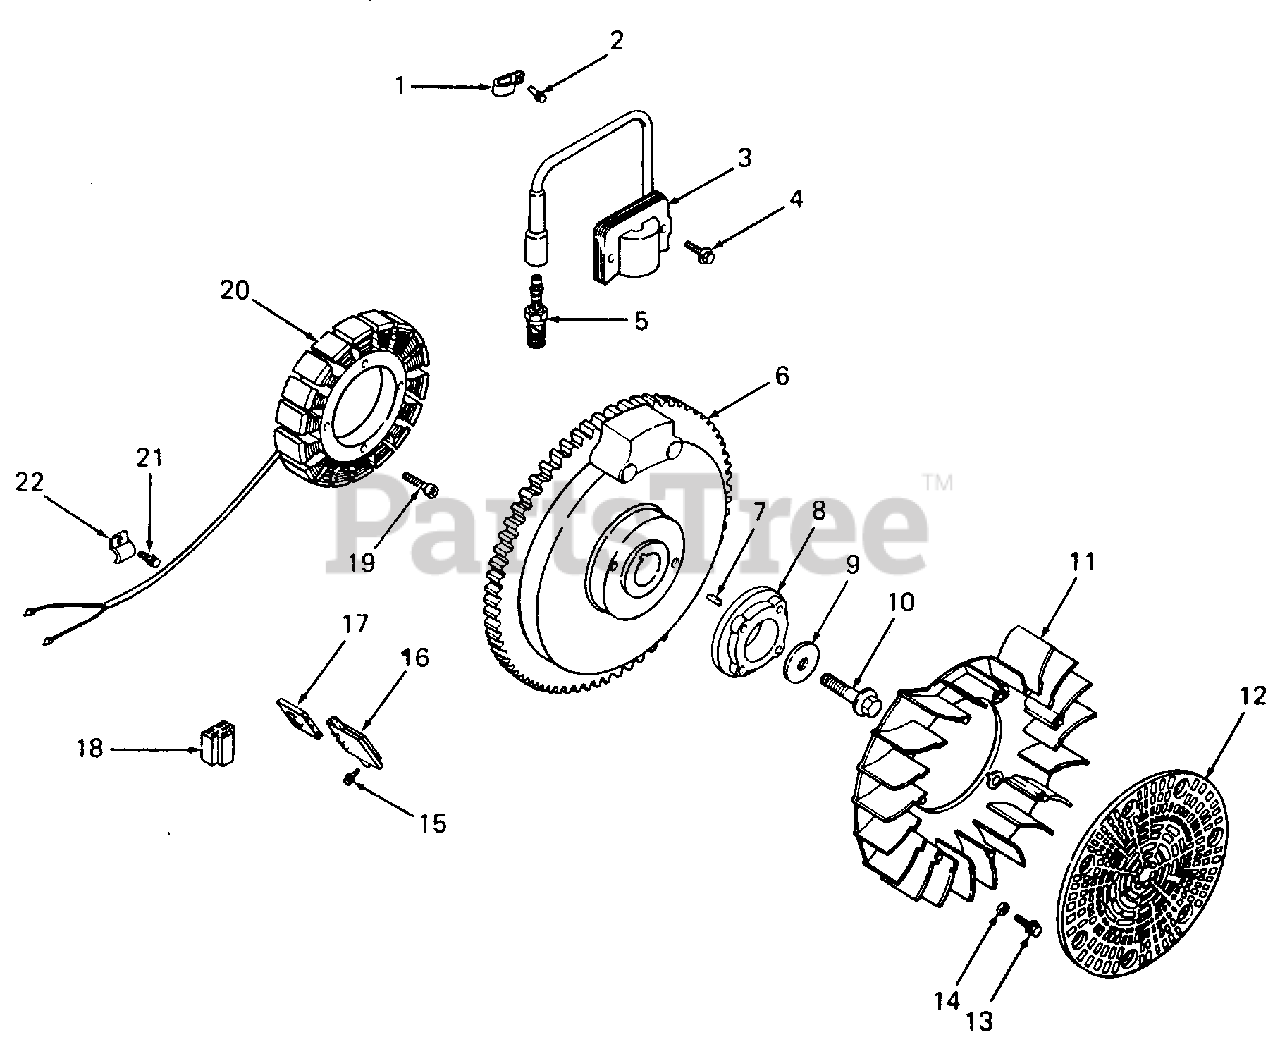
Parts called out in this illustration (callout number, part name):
1	Clip, Kill Lead
2	Screw, Lead Clip, M5 X 0.8 X 10
3	Module, Ignition
4	Screw, Ignition Module, M5 X 0.8 X 20
5	Spark Plug
9	Washer, Flywheel, 1-3/8 OD
10	Screw, Flywheel, M10 X 1.5 X 45.8
11	Fan
12	Screen, Grass
13	Screw, Fan, M6 X 1.0 X 16
14	Spacer, Fan
15	Screw, Rectifier-Regulator, M6 X 1.0 X 16
16	Rectifier-Regulator
17	Connector, Rectifier-Regulator (3 Contact)
18	Connector (5 Contact)
19	Screw, Stator Mounting, M5 X 0.8 X 25
20	Stator, 15 Amp
21	Screw, Stator Harness Clip, M5 X 0.8 X 10
22	Clip, Stator Harness
